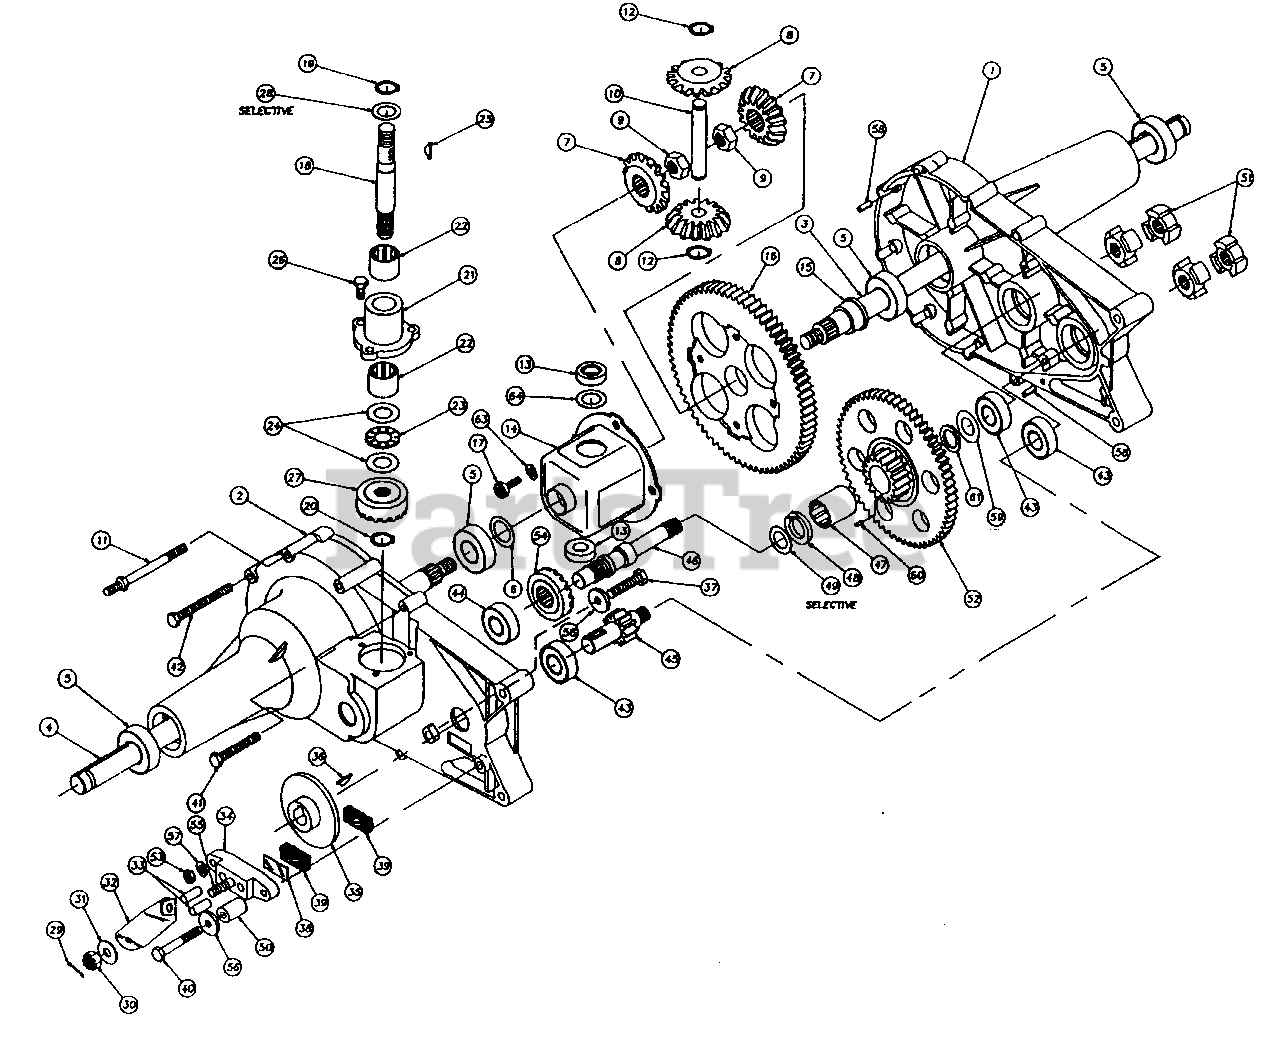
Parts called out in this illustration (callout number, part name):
1	Housing, Half L.H.
2	Housing, Half R.H.
3	Axle L.H.
4	Axle R.H.
5	Bearing, Ball
6	Washer, Flat 3/4 x 1-1/8 x .030
7	Gear, Miter
8	Gear, Miter
9	Nut, Hex Jam w/Patch 1/2-20
10	Shaft, Cross
11	Screw, Stud
12	Snap, Ring
13	Bearing, Thrust
14	Housing Assembly, Differential
15	Bearing, Flange
16	Gear, Differential 72 Tooth
17	Bolt, Torx Head 1/4-28 x 5/8"
18	Shaft, Input
19	Snap, Ring
20	Retaining Ring 7/16"
21	Housing, Input Bearing
22	Bearing, Needle
23	Bearing, Thrust
24	Washer, Flat 5/8 x 1-1/8 x .030
25	Key, Hi-Pro 3/32 x 5/8
26	Screw, Hex W/Patch 1/4-20 x 3/4
27	Gear, Input Pinion 17 Tooth
28	Washer, Flat .62 x 1 x .05
29	Pin, Cotter
30	Nut, Castle 5/16-24
31	Washer, Flat .343 x .88 x .062
32	Arm, Brake Actuator
33	Pin, Brake Actuating
34	Brake, Yoke
35	Disc, Brake
36	Key, Hi-Pro 3/16 x 5/8"
37	Screw, Hex 1/4-20 x 1.50
38	Plate, Puck
40	Screw, Hex w/Patch 1/4-20 x 2.00
41	Screw, Hex Self-Tap 1/4-20 x 2.00
42	Screw, Hex Self-Tap 1/4-20 x 3.00
43	Bearing, Ball
44	Bearing, Ball
45	Shaft, Pinion W/11 Tooth Gear
46	Shaft, Drive
47	Bearing, Needle
48	Bronze Thrust Brg. 5/8 x 1-1/4 x 7/64
49	Washer, Flat .62 x 1.0 x .040
50	Spacer
51	Coupling
52	Gear, 60 and 17 Tooth
53	Nut, Hex 1/4-20
54	Gear, Drive Pinion 17 Tooth
55	Bolt, Square Head
56	Washer 15/16 x .265 x .125
57	Washer, Spring Lock 1/4"
58	Pin, Roll 3/16" x 1/2"
59	Washer, Flat .62 x 1.0 x .030
60	Pin, Dowel 3/32 x 1/4
61	Seal, Grease
